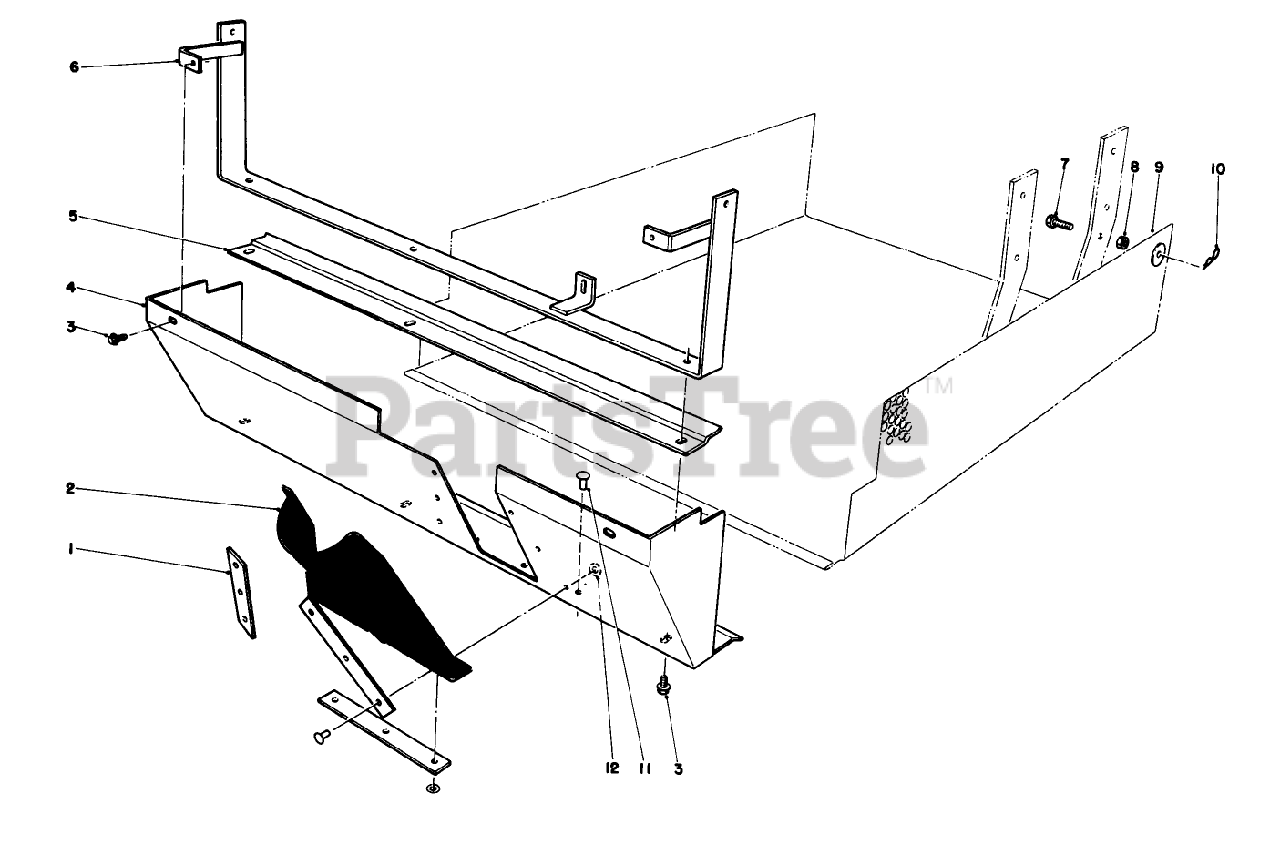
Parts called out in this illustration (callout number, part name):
2	RUBBER SHIELD
3	SCREW
6	DEFLECTOR MT WA *R
8	NUT-LOCK, NI
10	PIN-COTTER, HAIR
11	RIVET-POP
12	WASHER-FLAT
